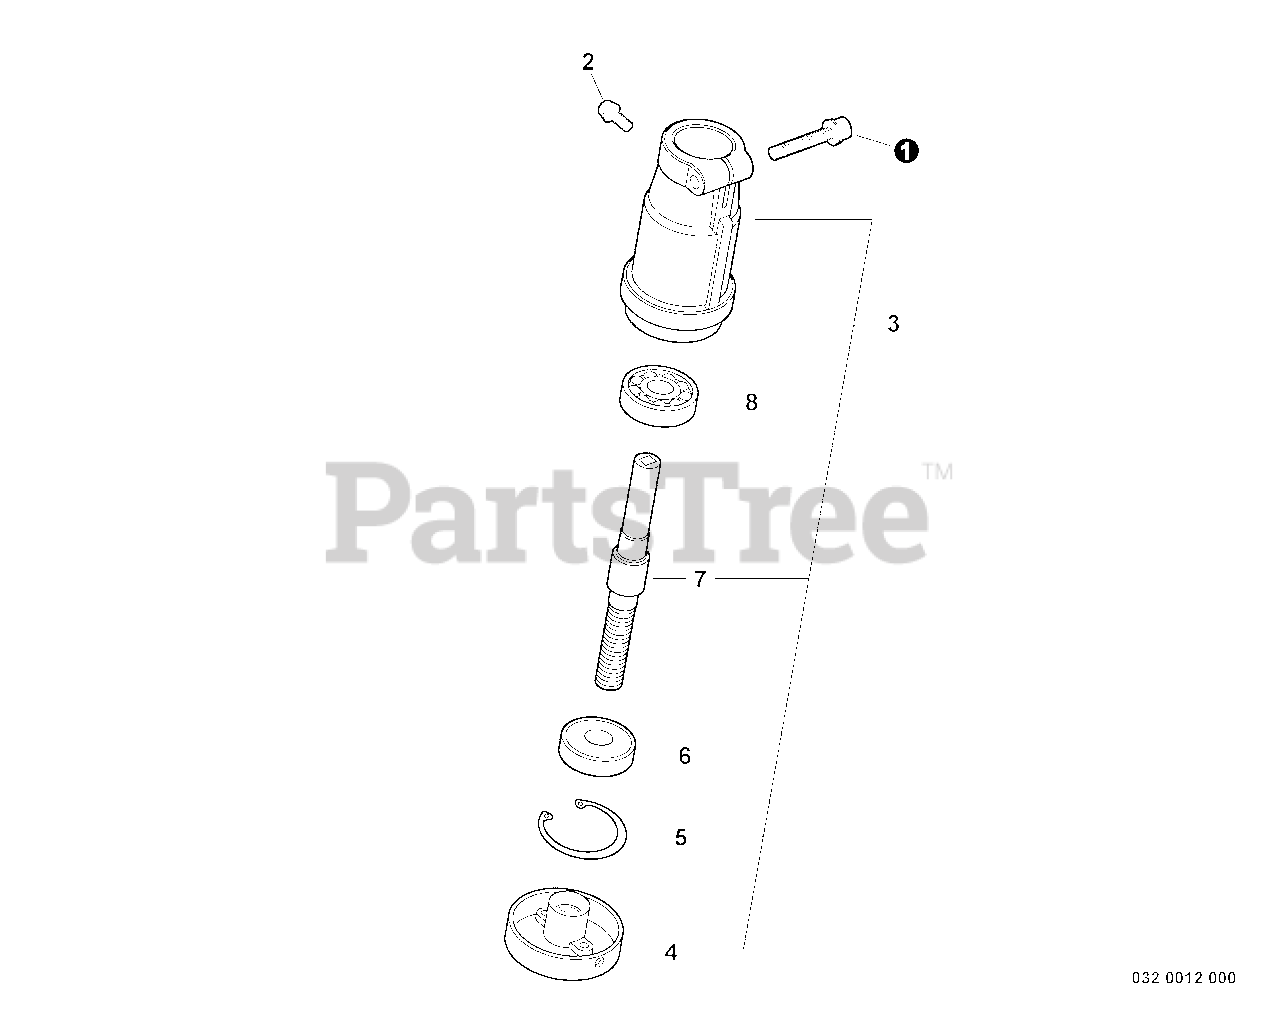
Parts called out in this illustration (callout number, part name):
1	BOLT 5×25
2	SCREW 4×10
3	GEAR CASE ASSY
4	PLATE, ADAPTOR - UPPER
5	E-RING 30
6	BEARING, BALL 6200
7	SHAFT, GEAR
8	BEARING, BALL 6200
